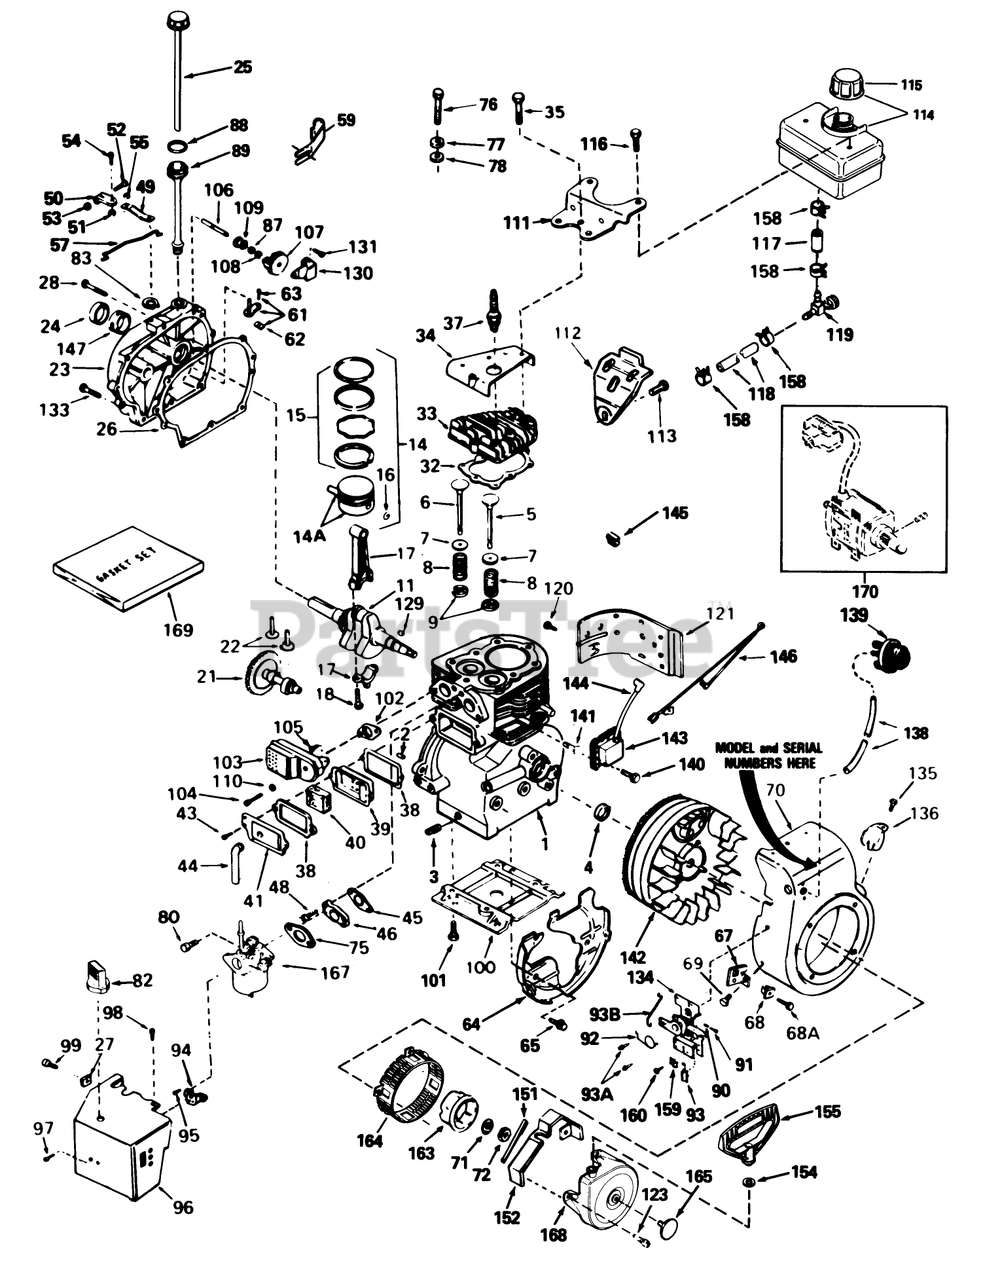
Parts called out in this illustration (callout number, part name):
1	Cylinder Assy. (Incl. Ref. #2, 3 4)
2	Pin-Dowel
3	Plug-Drain, Oil (SQH 1/4-18)
4	Oil Seal
5	Valve, Intake (Standard)(Incl. No. 9)
5	Valve, Intake (1/32" oversize)(Incl. No. 9)
6	Valve, Exhaust (Standard)(Incl. No. 9)
6	Valve, Exhaust (1/32" oversize)(Incl. No. 9)
7	Cap-Spring, Valve
8	Spring-Valve
9	Keeper-Spring, Valve
11	Crankshaft Assy. (Incl. Ref. #12 13)
14	Piston, Pin Ring Assy. (Std.)(Incl. Ref. #14A, 15 16)
14	Piston, Pin Ring Assy. (.010 Oversize)(Incl. Ref. #14A, 15 16)
14	Piston, Pin Ring Assy. (.020 Oversize)(Incl. Ref. #14A,15 16)
14A	Piston Pin Assy. (Std.)(Incl. Ref. #16)
14A	Piston Pin Assy. (.010 Oversize)(Incl. Ref. #16)
14A	Piston Pin Assy. (.020 Oversize)(Incl. Ref. #16)
15	Ring Set (Std.)
15	Ring Set (.020" OS)
15	Ring Set (.010" OS)
17	Rod Assy., Connecting (Incl. Ref. #18)
18	Bolt-Connecting Rod
21	Camshaft
22	Lifter-Valve
23	Cover, Cylinder (Incl. Nos. 24 106)
24	Oil Seal
25	Dipstick
26	Gasket-Cover, Cylinder
27	Nut-U Type
28	Screw (1/4-20 x 1-1/4)
32	Gasket-Cylinder Head
33	CYLINDER HEAD
34	Cover-Head, Cylinder
35	Screw (5/16-18 X 2-1/2)
37	Spark Plug-Resistor (R J19 L M)
38	Gasket-Cover, Valve
39	Body-Breather
40	Element-Breather
41	Cover-Valve
43	Screw
44	Tube-Breather
45	Gasket-Pipe, Intake
46	481-1279 SENATOR RO
48	Screw
49	Lever-Governor
50	Clamp-Lever, Governor
51	Nut-Lock
52	Screw
53	Nut-Lock
54	Screw
55	Washer-Lock
57	Governor Link
59	Clip-Tube, Fill
61	Rod, Governor (Incl. Nos.62 63)
62	Yoke-Governor
63	Screw (6-40x5/16)
64	Baffle-Blower Housing
65	Screw (1/4-20x19/32)
67	Bracket
68	Grommet
68A	Screw (8-32 x 3/8)
69	Screw
70	Housing, Blower (Incl. Ref. #135 136)
71	Washer-Belleville
72	Flywheel Nut
75	Gasket-Carburetor
76	Screw (5/16-18 X 2-1/2)
77	Washer-Belleville
78	Washer-Flat
80	Screw (T-30, 1/4-20 X 27-32)
82	Knob-Choke
83	Ring-Retaining
87	Washer
88	O-Ring
89	Tube-Fill, Oil
90	Spring-Compression
91	Screw
92	Spring-Throttle
93	Terminal
93A	Screw (10-32 x 1/2)
93B	Link-Throttle
94	Bracket-Choke
95	Screw (10-32 x 1/2)
96	Carburetor Cover
97	Screw (8-32 X 5/16)
98	Screw (10-32x1/2)
99	Screw (8-32 x 3/8)
100	Base Engine
101	Screw
102	Gasket-Muffler
103	Muffler
104	Screw (5/16-18 X 2)
105	Screw
106	Shaft-Governor
107	Governor Gear ASM
108	Ring-Retaining
109	Spool-Governor
110	Washer
111	Plate, Fuel Tank Mounting
112	Bracket, Fuel Tank Mounting
113	Screw (1/4-20x19/32)
114	Tank Assembly-Fuel (Incl. Ref. #250 253)
115	Cap-Fuel
116	Screw (1/4-15x7/8)
117	Line-Fuel
118	Line-Fuel (8.62)
119	Valve-Shut Off
120	Screw
121	Extension-Blower Hsng.
123	Screw
129	Key-Flywheel
130	Bracket, Governor
131	Screw (10-24x1/2)
133	Screw
134	Control Assy., Remote Speed (Incl. Ref. #90 thru 93)
135	Screw (8-32 x 3/8)
136	Screw
138	Line-Primer
139	Primer-Asm
140	Screw
142	Flywheel
143	Solid State
144	Cover-Spark Plug
145	Clip-Wire
146	Ground Wire
147	Bushing-Crankshaft
152	Guard-Starter
153	Seal, Snowguard
154	Washer
155	Handle-Starter, Mitten Grip
158	Clamp-Line, Fuel
159	Conduit
160	Screw (10-32 x 3/8)
163	Cup-Starter
164	Screen-Starter
165	Plug Starter
167	Carburetor (Incl. Ref. #1-28)
168	Starter-Rewind
169	Gasket Set
170	Electric Starter Kit #33328C (Optional)-Order as an accessory.
